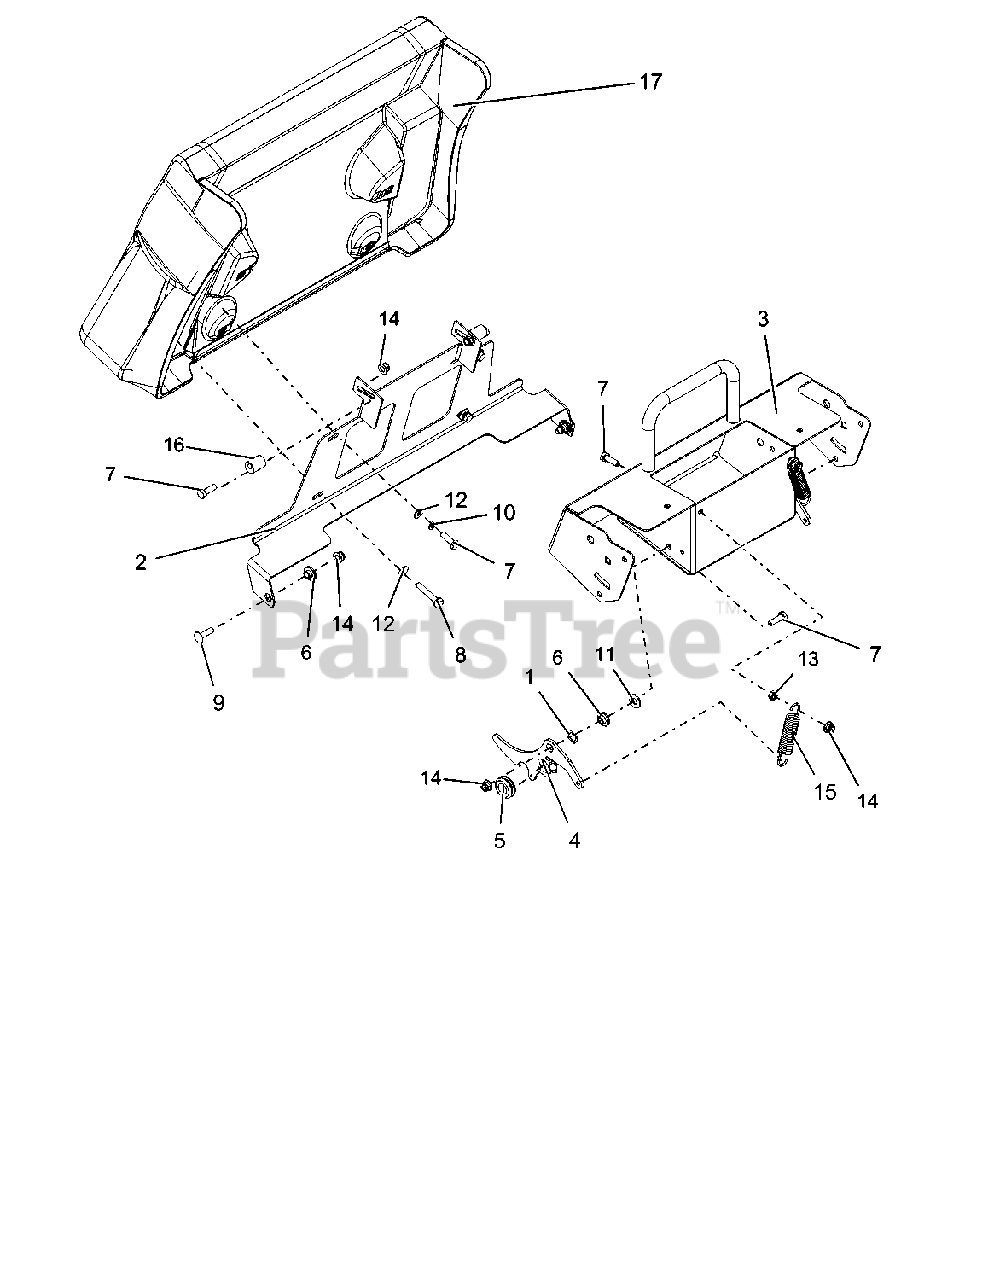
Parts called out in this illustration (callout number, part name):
1	WAVE WASHER .531X.781X.125FH
2	PAD, MOUNT
3	WLDMT, CONTROL PANEL PROSTANCE
4	LATCH, PAD MOUNT
5	GROMMET, SPLIT RUBBER
6	BSHG-FLG .32X.500X.344X.880
7	@BLT-HEX .31-18X1.00 GR5 YWZC
8	@BLT-HEX .31-18X1.75 GR5 YWZC
9	BLT-RDHDSQSHNK.31-18X1.13 G5YZ
10	@WSHR-LK .31X.078 REG YWZC
11	@WSHR-FL-STL.38X.875X.083 YWZC
12	@WSHR-FL-STL.312X.734X.065 YWZ
13	@NUT-LK-CTR-JAM .31-18 YWZC
14	@NUT-LK-NYL-FLG .31-18 YWZC
15	SG-TENS .105X.812X3.88 WLD 15
16	ECCENTRIC
17	PAD, PRO-STANCE OPERATOR
